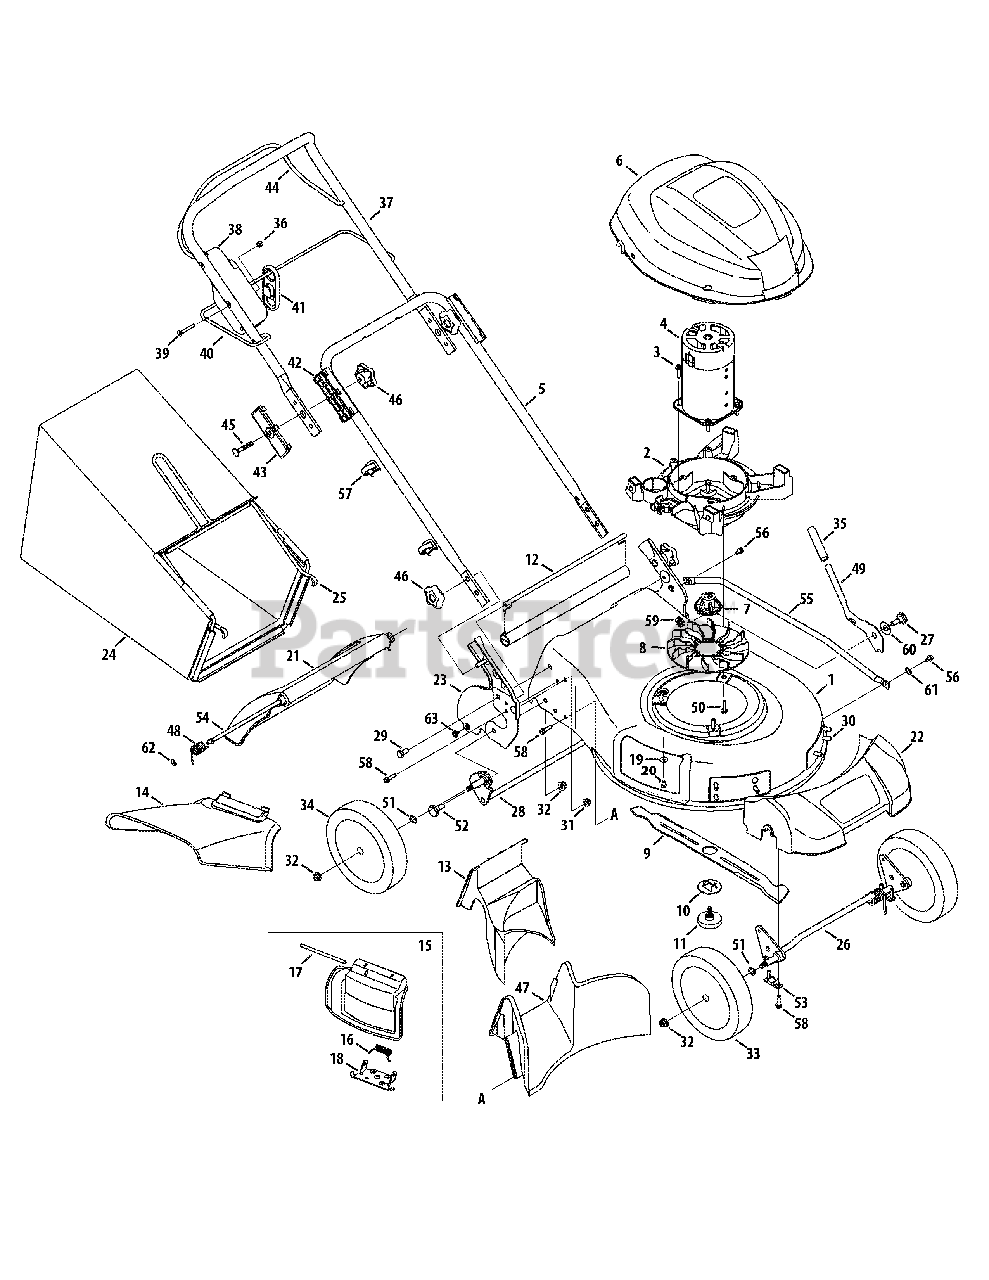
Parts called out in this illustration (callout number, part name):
1	19" Deck - MTD Red
1	19" Deck - Black Jack
2	Motor Bracket
3	Screw, 1/4-15 x .750
4	Electric Motor, 120V
6	Motor Shroud
7	Blade Hub
8	Electric Fan
9	Mulching Blade
10	Blade Locking Plate
11	Blade Bolt Assembly
12	Trail Shield
13	Rear Mulch Plug
14	Side Discharge Chute
15	Mulch Plug (Incl. 16-18)
16	Torsion Spring
17	Hinge Pin
18	Chute Deflector Adapter
19	Beleville Washer
20	Screw
21	Rear Door
22	Front Cover
23	Handle Bracket - RH
23	Handle Bracket - LH
24	Grass Bag
25	Grass Bag Frame
26	Front Bracket Assembly
27	Screw, Shoulder, .50 x .66
28	Rear Bracket Assembly
29	Screw, 5/16-18 x .625
30	Screw, 5/16-14 x .750
31	Nut, Flange Lock, 5/16-18
32	Nut, Flange Lock, 3/8-16
33	Front Wheel
34	Rear Wheel
35	Foam Grip
36	Nut, Hex Lock, 1/4-20
37	Upper Handle
38	Motor/Blade Control
39	Screw, Flat, 1/4-20 x 1.75
40	Guide Rod
41	Cord Retainer
42	Lower Handle Insulator
43	Upper Handle Insulator
44	Motor/Blade Control Handle
45	Bolt Carriage, 5/16-18 x 2.50
46	Star Knob
47	Rear Baffle
48	Door Torsion Spring - RH
48	Door Torsion Spring - LH
49	Spring Lever
50	Screw, 5/16-12 x .750
51	Washer, Wave, .510 x .750 x .017
52	Screw, Shoulder, .500 Dia. X .434
53	Bushing, Lock, .505 Dia. X .62
54	Rear Door Pivot Rod
55	Cross Bracket
56	Screw, Shldr., 1/4-20 x .50
57	Cable Guide
58	Screw, 1/4-15 x 1.000
59	Spacer, .515 x 1.00 x .310 Lg.
60	Washer, Bell, .510 x 1.14 x .040
61	Washer, Wave, .385 x .598
62	Nut, Speed
63	Screw, #10-16 x .375
